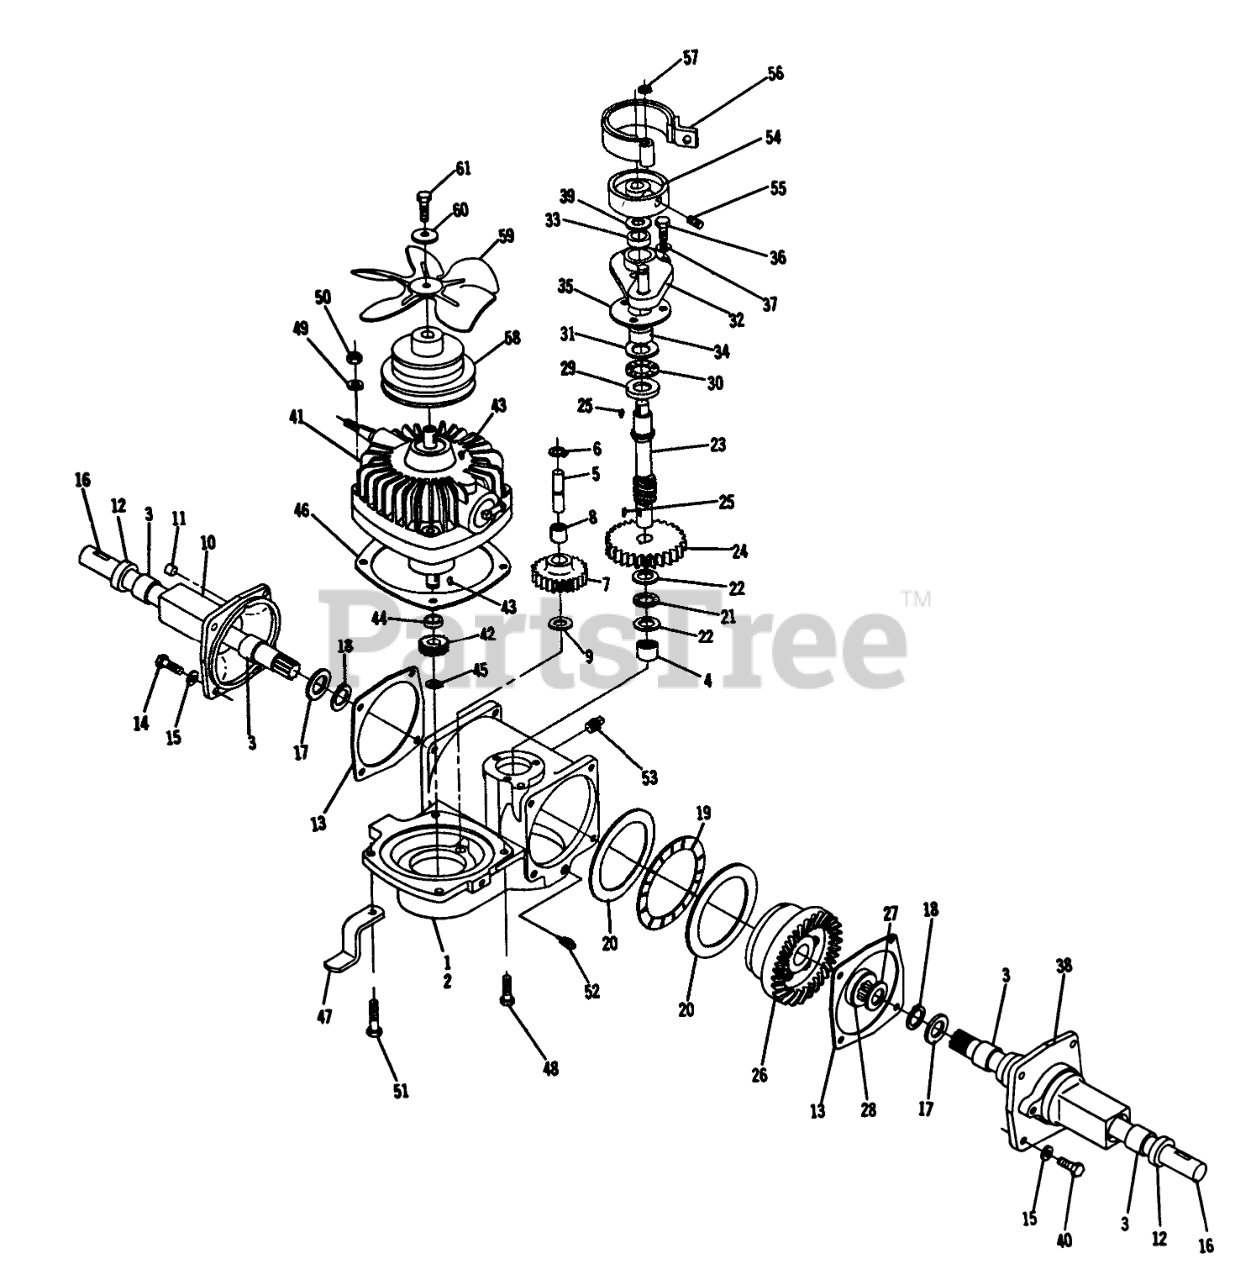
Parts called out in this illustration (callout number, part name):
1	Transmission Less Pump Brake Ass-y.
2	Housing
3	BEARING-NEEDLE
4	BEARING-NEEDLE
9	RACE THRUST
11	Breather
14	Bolt 3/8-16 x 1
15	Lockwasher
25	KEY WOODRUFF
26	BULLT 325
28	Bearing Axle
31	Rae-Thrust
36	Bolt 5/16-18 x
38	Housing Axle L.H.
39	WASHER-THRUST
40	Bolt 3/8-16 x 1
41	Engine Speed Control
43	KEY WOODR 1/8X1/2 DI
47	Bracket-Stop
48	Bolt Hex 3/8-16 x 1
49	Washer
50	3/8-16 E.S.
51	Bolt 3/8-16 x 3 3/4"
52	Plug 1/4 Pipe
55	Screw 1/4-20 x 5/8
59	FAN
61	Bolt Hex 1/4-20 x 1 1/4 Nylok
